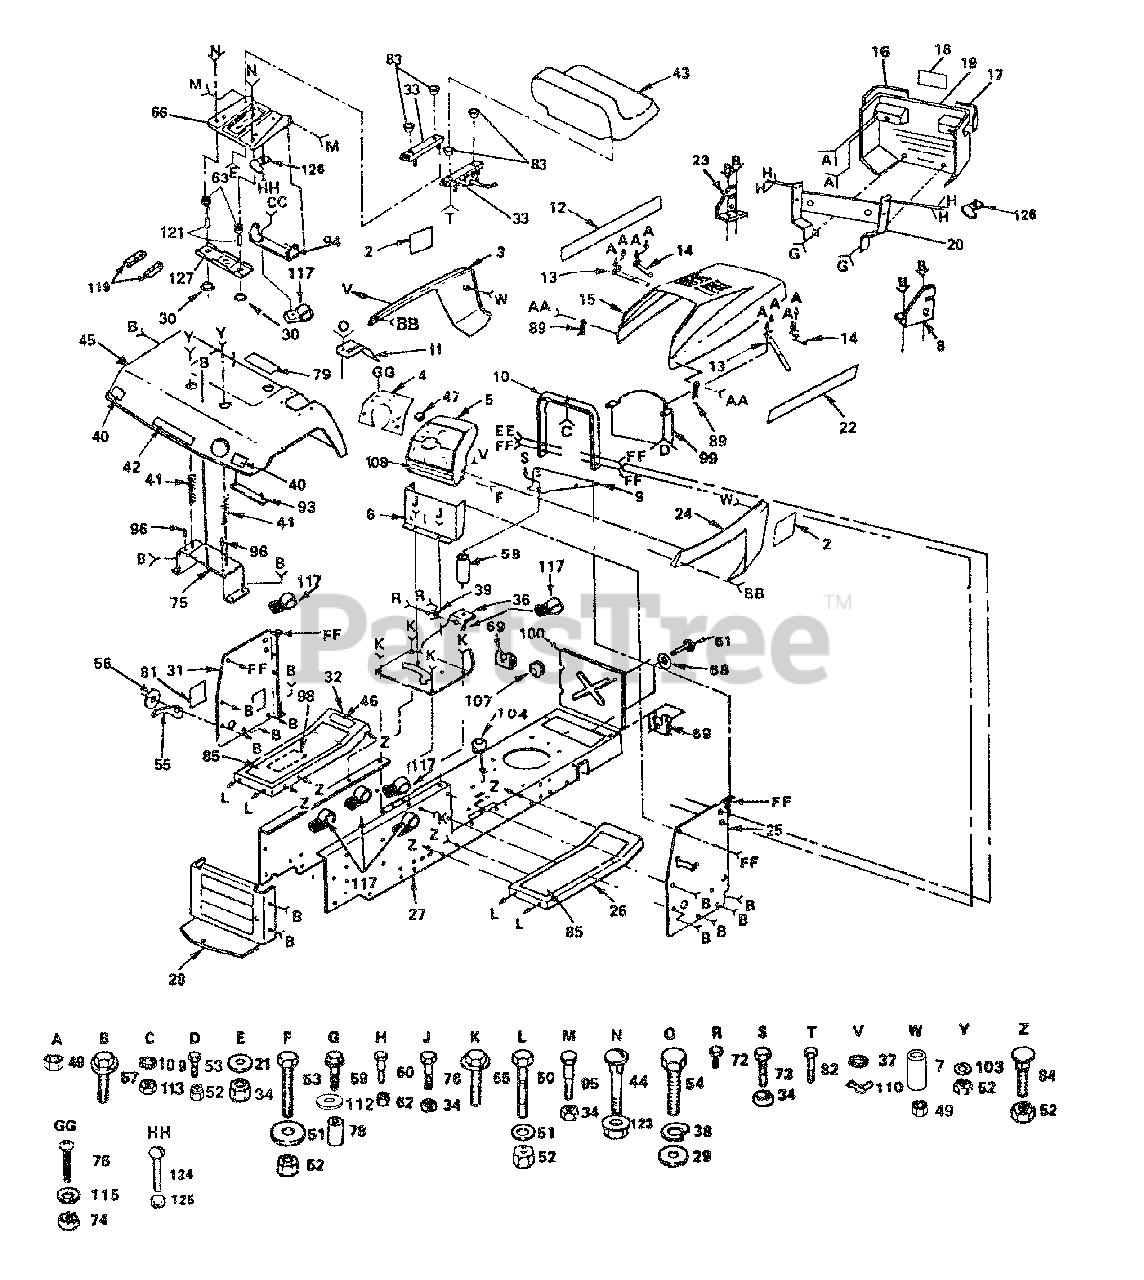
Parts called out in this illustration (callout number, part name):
2	Decal-Side Panel
3	Panel-Side, L.H.
4	Dash, Plate
5	Dashboard
6	Dash, Assembly-Lower
8	Bracket, Assembly R.H.
9	Plate-Support, Battery
10	Support, Assembly-Dash
11	Console, Shifter
12	Decal-Hood, L.H.
13	Strap, Assembly-Hinge, Rear
14	Strap, Assembly-Hinge, Front
15	Hood
16	Lens, L.H.
17	Lens, R.H.
18	Decal, Grill
19	Grill, Assembly
20	Support Assembly, Grill
21	Washer 11/32 x 1 x 10 Ga.
22	Decal-Hood, R.H.
23	Bracket, Assembly L.H.
24	Panel-Side, R.H.
25	Panel-Dash, R.H.
26	Footrest-R.H.
28	Drawbar
29	Washer 3/16 x 7/16 x 18 Ga.
30	Bushing, Snap
31	Panel-Dash, L.H.
32	Footrest-L.H
33	Slide Set, Seat
34	Locknut 5/16- 18
36	Saddle
37	Washer, Lock 1/4 Int./Ext.
38	Washer, Lock #8
39	Bushing-Steering
40	Reflector-Taillight
41	Spring-Compression
42	Decal-Fender
43	Seat
44	Bolt, Carr. 1/4-20 x 1-1/4
46	Decal-Clutch/Brake
49	Nut, Hex 1/4-20
50	Bolt-Hex 3/8-16 x 3/4
51	Washer 13/32 x 13/16 x 12 Ga.
52	Nut-Crownlock 3/8-16
53	Bolt-Hex 3/8-16 x 1
54	Screw #8-3/8
55	Pointer, Height Indicator
56	Washer, Nylon
57	Screw-Hex Washer Hd. Thd. Rolling.,3/8-16 x 3/4 Type TT
59	Bolt, Hex 1/4-20 x 1-1/2
60	Bolt-Shoulder 1/4-20
61	Stud 1/4 Turn
62	Nut-Crownlock 1/4-20
63	Spring, Compression
65	Screw-Hex Washer Hd. Thd.Forming 3/8-16 x 1/2 Type TT
68	Retainer 1/4 Turn
69	Receptacle 1/4 Turn
72	Screw-Hex Head Self Tapping #10 16 x 1/2 Type B
73	Bolt-Hex 5/16 -18 x 2 Gr 2
74	Nut-Keps 5/16-18
75	Bracket Assembly-Fender
76	Screw,Mach. 5/1 6-18 x 3/4
79	Decal-OPEI-Caution
81	Cover-Access
82	Screw, Hex 5/16-18 x 1
84	Bolt-Carriage 3/8-16 x 3/4
85	Pad-Footrest
89	Latch-Hood
93	Strap Assembly Fender
94	Bracket-Pivot, Seat
95	Bolt-Shoulder 5/16-18
98	Decal-V-Belt Drive Schematic Tractor
99	Baffle-Rear Upper
100	Baffle-Rear Lower
103	Washer 13/32 x 1 x 14 Ga.
107	Grommet, Split
108	Decal, Operating Instructions
109	Washer, Lock 114 Int. Ext.
110	Wingnut 1/4-20
112	Washer 9/32 x 3/4 x 16 Ga
113	Nut-Hex 1/4-20
115	Washer 11/32 x 11/16 x 16 Ga.
117	Clip, Insulated
119	Foam Strip
121	Spacer Split 0.28 x 0.88
123	Locknut, Hex, Large Flanged 1/4-20 UNC
124	Screw, Slotted Pan Head #10-32 x 1/2
125	Nut, Keps #10-32 UNC
126	Clip, insulated
127	Bracket, Switch Mount
